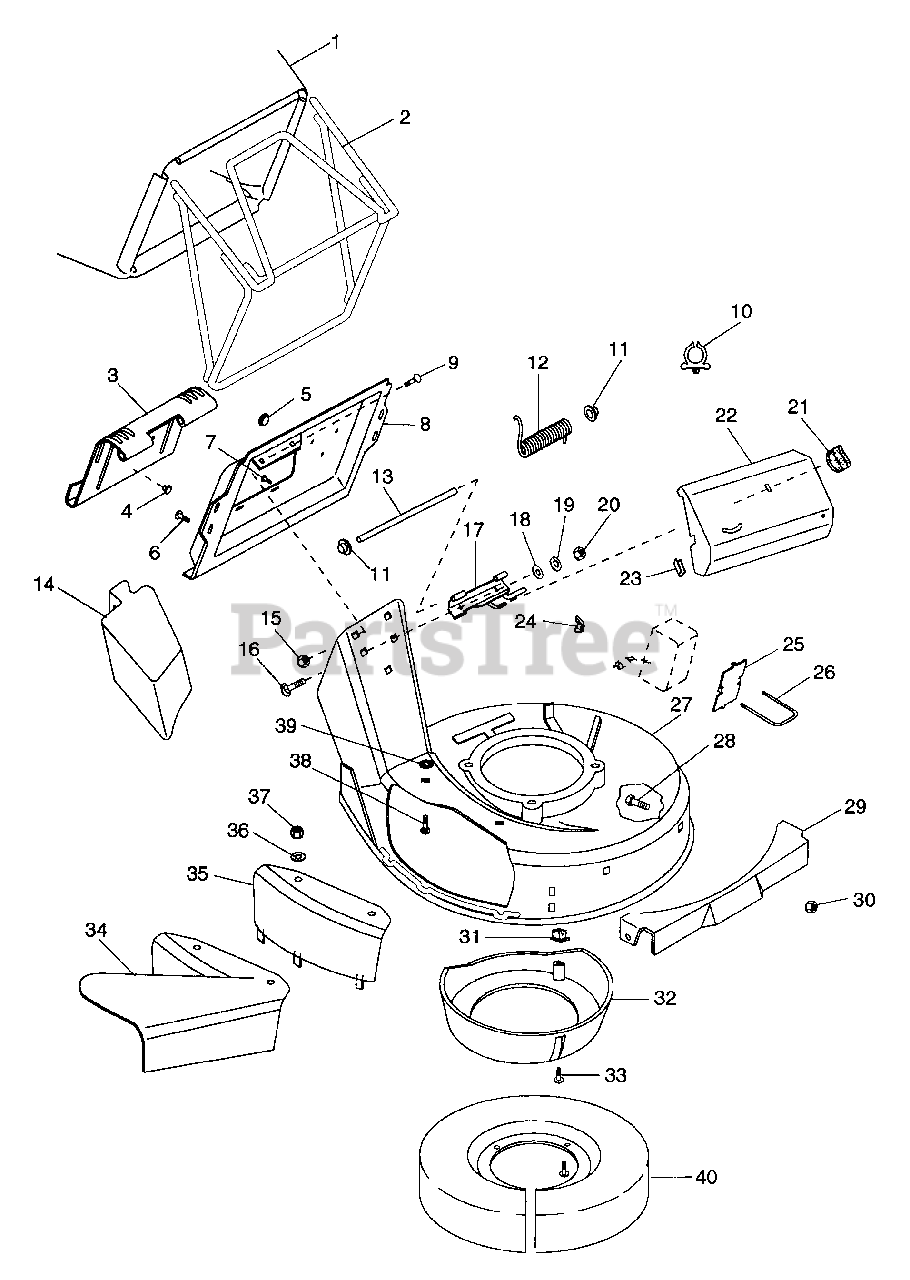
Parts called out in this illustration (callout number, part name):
1	BAG,CONSUMER BLACK 15 OZ/YD2
2	BAGGER FRAME
3	CATCHER PLATE DOOR
4	BUTTON BUMPER
6	SCR-TAP 12-24X.50 HWH PL TR
7	SCR-TAP 10-24X.375 TORX PHD
8	CATCHER PLATE
9	@BLT-RHDSSQNK .25-20X.38 G2YZ
10	SNAP-IN CLIP
11	PUSH NUT, .25
12	SG-TORS .120X.68X3.09
13	DOOR PIN
14	MULCH MASTER MULCHER ACCESSORY
15	NUT-LK-FLG .250-20 PL
16	BLT-RDHDSQNK .25-20X.62 PL
17	HINGE BASE
17	HINGE BASE WELDMENT
18	WSHR-FL-STL .380X.875X.179 PL
19	WSHR-LK .250X.077 HVY PL
20	NUT-HEX .250-20 PL
21	WING - NUT
22	DRIVE COVER
23	TRIM BUMPER
24	NUT-WING 8-32
25	HOLD DOWN PLATE
26	U-BOLT
27	MOWER PAN W/DECALS PUSH
27	MOWER PAN W/DECALS SP/COMM
27	MOWER PAN W/DECALS SP
28	BLT-RDHDSQSHNK .31-18X.50 YZ
29	FRONT PANEL
30	NUT-LK .312-18 GR A PL
31	PLASTIC GROMMET
32	CENTER BAFFLE
33	SCR-TAP 10-16X.62 SLPH PL AB
34	SIDE DISCHARGE ASSEMBLY
35	SIDE DISCHARGE COVER
36	WSHR-FL-STL .38X.875X.083 PL
37	NUT-LK-NYL.312-18 PL
38	BLT-RDHDSQNK .31-18X.75 SHT PL
39	NUT-PUSH .312
40	MULCHMASTER DOME INSERT
